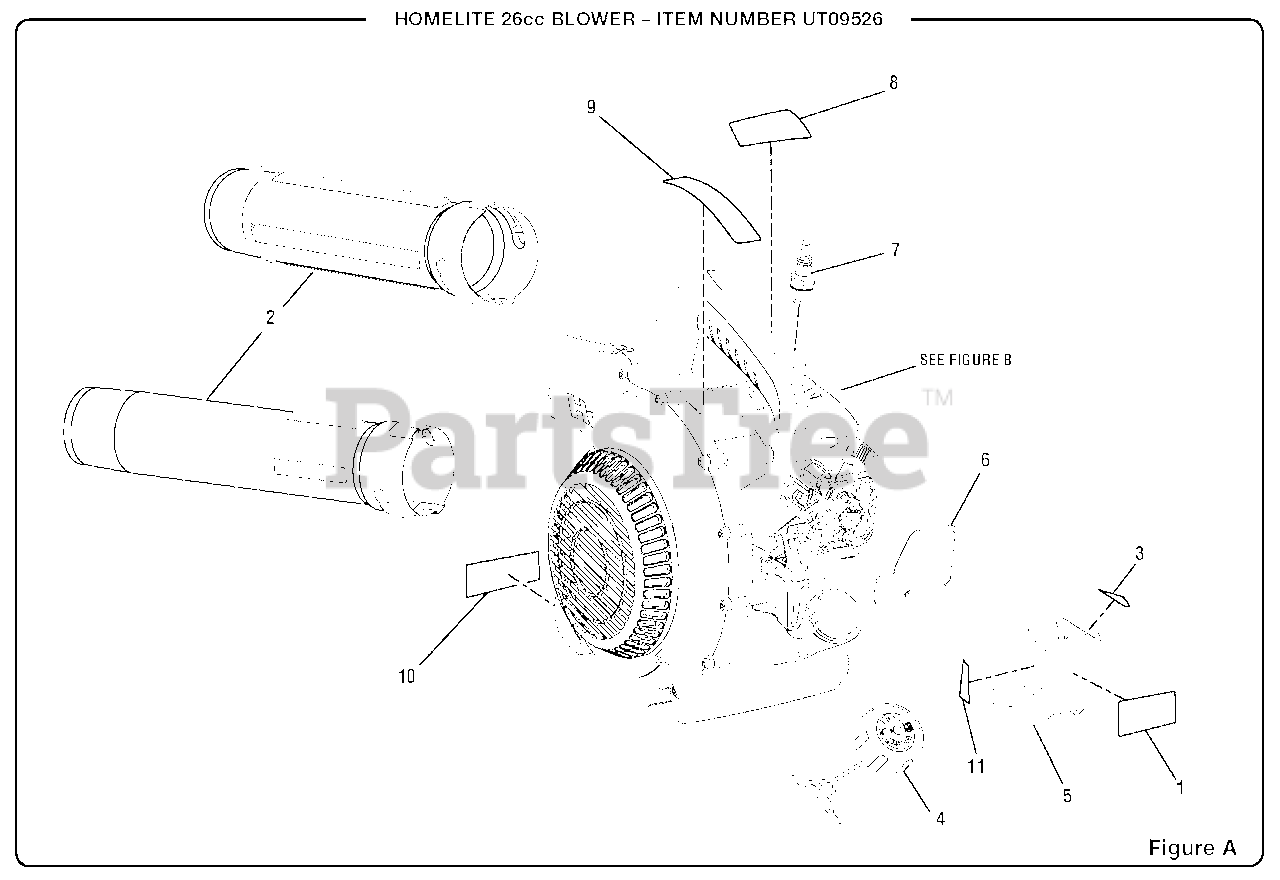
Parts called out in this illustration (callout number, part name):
1	Starting Instructions Label
2	Sweeper Nozzle & Upper Blower Tube Assembly
3	Throttle Label
4	Fuel Cap Assembly
5	Air Box Cover
6	Air Box Gasket
7	Spark Plug (RCJ6Y)
8	Logo Label (Engine Shroud)
9	Warning Icon Label
10	Combustion Warning Label
11	Choke Label
